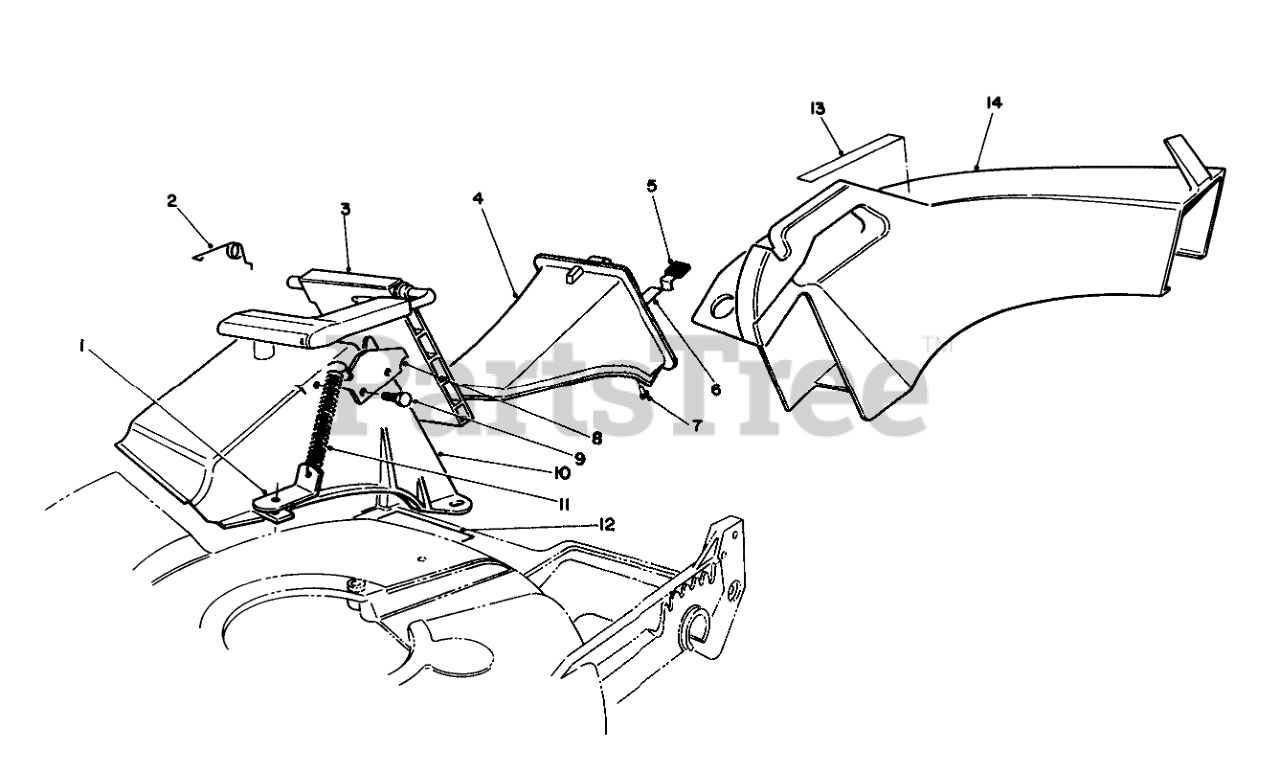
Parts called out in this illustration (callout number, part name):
1	Bracket-Spring
2	RETAINER-DOOR
3	DOOR ASSEMBLY
4	Plug Assembly (Incl. Ref. #5-7)
5	GRIP-LATCH
6	LATCH-PLUG, DISCHARGE
7	RIVET-HEAD, FLAT
8	DOOR LATCH PLATE
9	SCREW-PLASTITE
10	DISCHARGE TUNNEL
11	Spring-Door
12	DECAL - CAUTION
13	DECAL - WARNING
14	CHUTE
